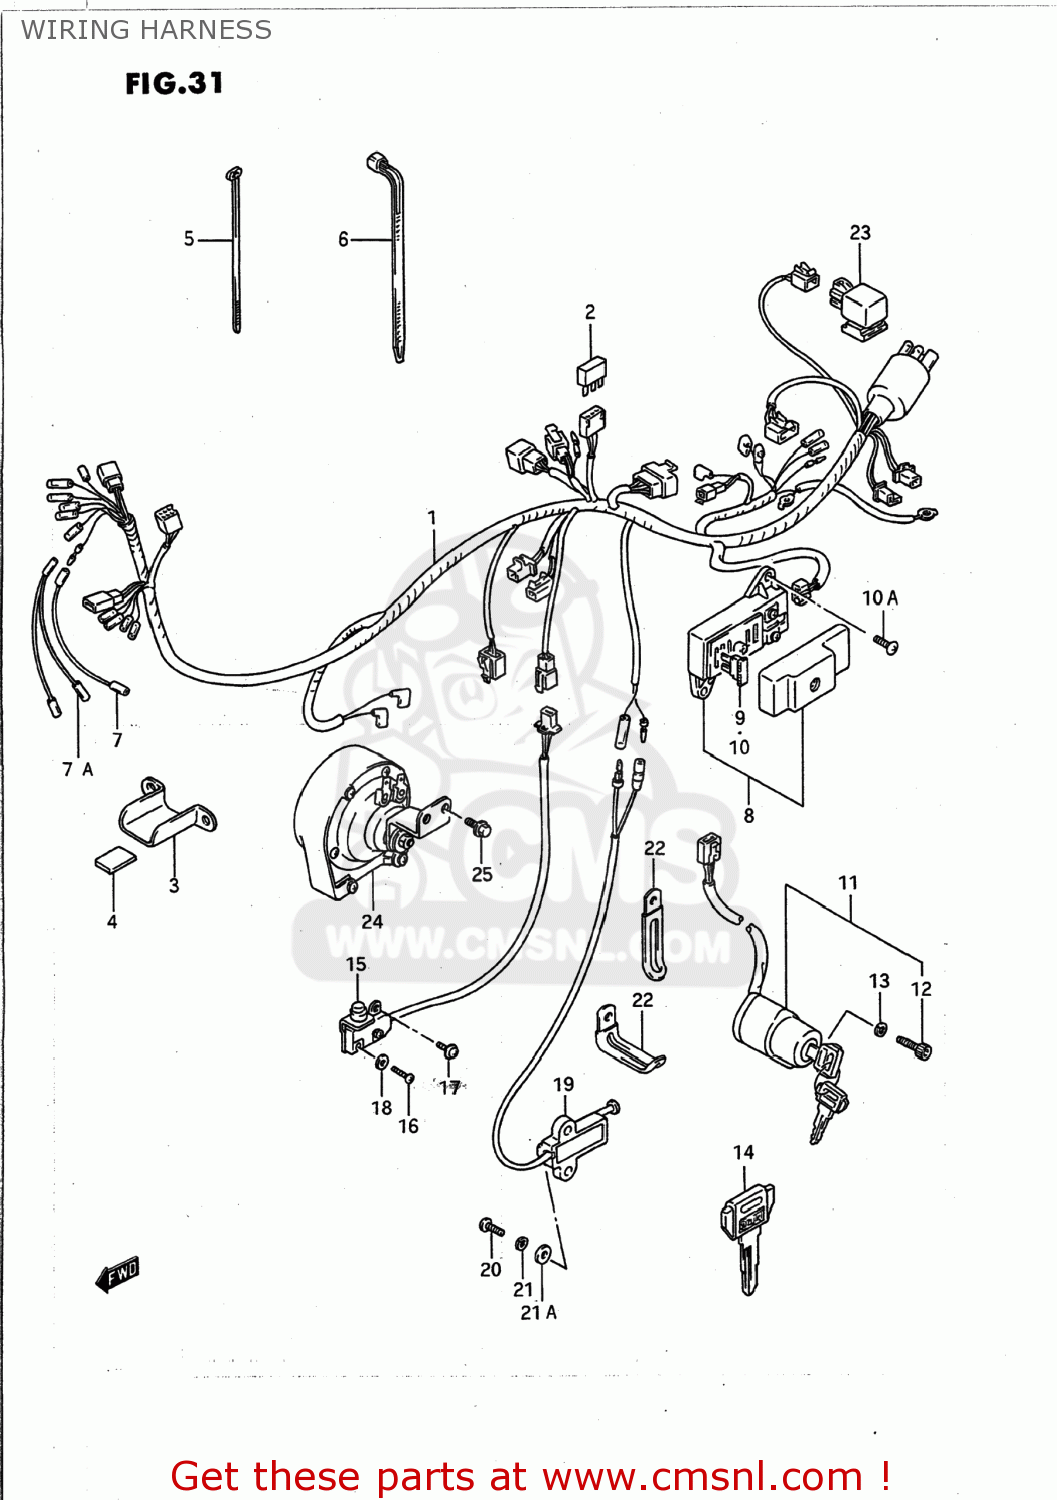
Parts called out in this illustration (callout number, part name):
1	HARNESS,WIRING
2	DIODE(STANLEY DE8804)
3	GUIDE,WIRING HARNESS
4	CUSHION
5	CLAMP
6	CLAMP L:165
7	WIRE
7A	WIRE,CLUTCH SW CONNECTOR
8	BOX ASSY,FUSE
9	FUSE (25A)
10	FUSE(10A)
10A	SCREW
11	SWITCH ASSEMBLY,IGNITION
12	BOLT
13	WASHER,LOCK
14	KEY,BLANK(TYPE:C)
15	SWITCH ASSY,STOP LAMP
16	SCREW
17	SCREW
18	WASHER
19	SWITCH ASSEMBLY,SIDE STAND
20	SCREW
21	WASHER,LOCK
21A	WASHER
22	CLAMP(L:45)
23	RELAY ASSY
24	HORN ASSY
25	BOLT
